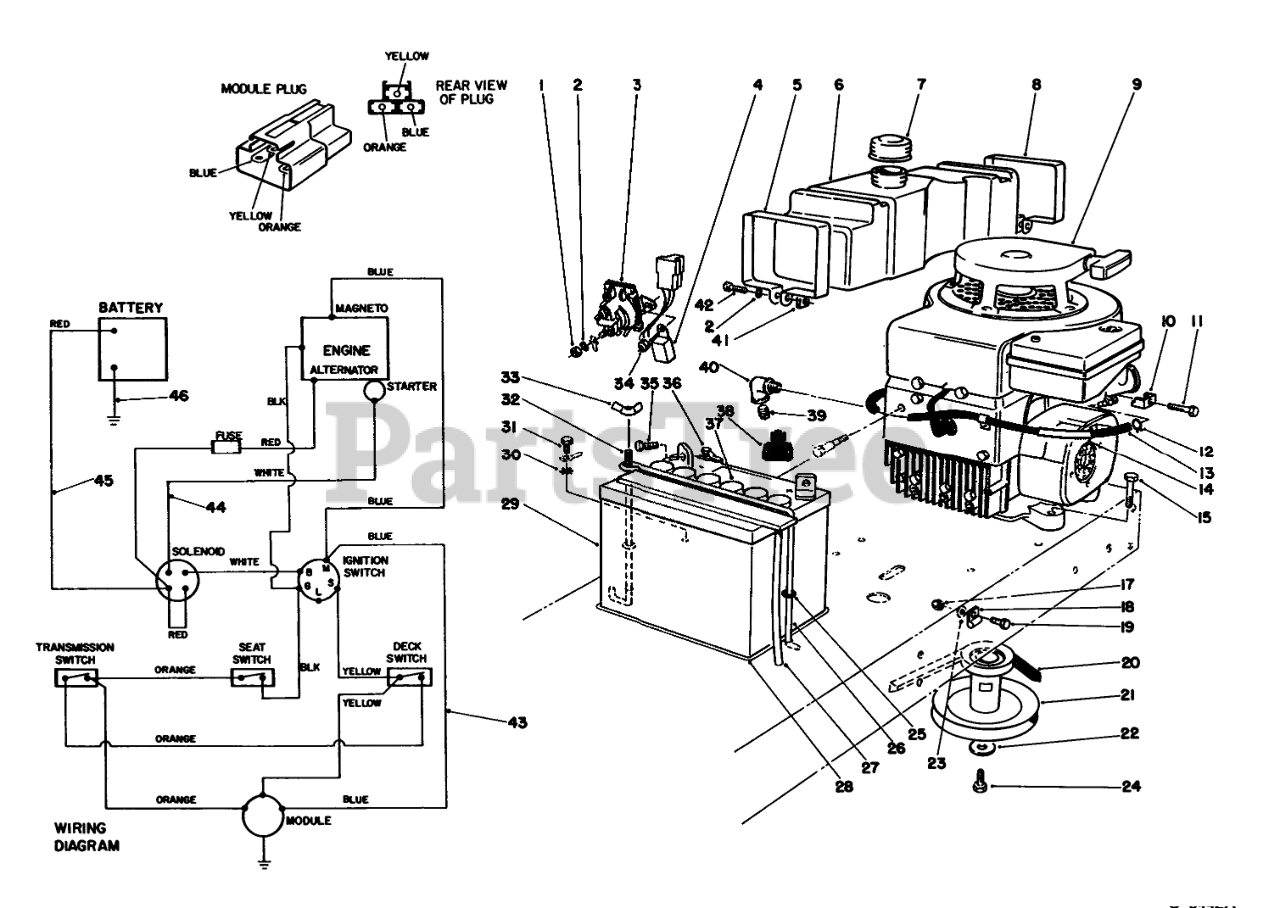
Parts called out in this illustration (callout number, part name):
1	NUT-JAM
2	WASHER-LOCK
3	SOLENOID
4	Module Interlock
5	Retainer-Front
6	TANK-5 QT GAS
7	GAS CAP ASM
8	Retainer-Tank Rear
9	Engine-12.5 H.P. B & S
10	CLAMP-CASING
11	SCREW W ENGINE
12	CLAMP-HOSE
13	HOSE - FUEL
14	SUPPORT-FUEL LINE
15	SCREW-HH
17	NUT-LOCK, NI
18	CLAMP
19	SCREW-HH
20	V-BELT, TRACTION
21	ENGINE PULLEY ASM
22	WASHER-FLAT
23	WASHER-PLAIN
24	SCREW-HH
25	O-RING
26	HOLDDOWN-BATTERY
27	TUBE-BATT DRAIN/80-2600
28	PAD-SKID, ANTI
29	Battery
30	WASHER-LOCK, INTERNAL
31	SCREW-HWHTF
32	POST-BATTERY
33	NUT-WING
34	NUT-LOCK, NI
35	SCREW-HH
36	NUT-WING
37	CAP-BATTERY
38	BOOT-TERMINAL
39	3/8 PIPE PLUG
40	ELBOW-STREET, 90 DEG
41	NUT-SQUARE
42	SCREW-HSH
43	WIRING HARNESS
44	WIRE HARNESS
45	WIRE ASM
46	WIRE ASM(BATT/GRD.
